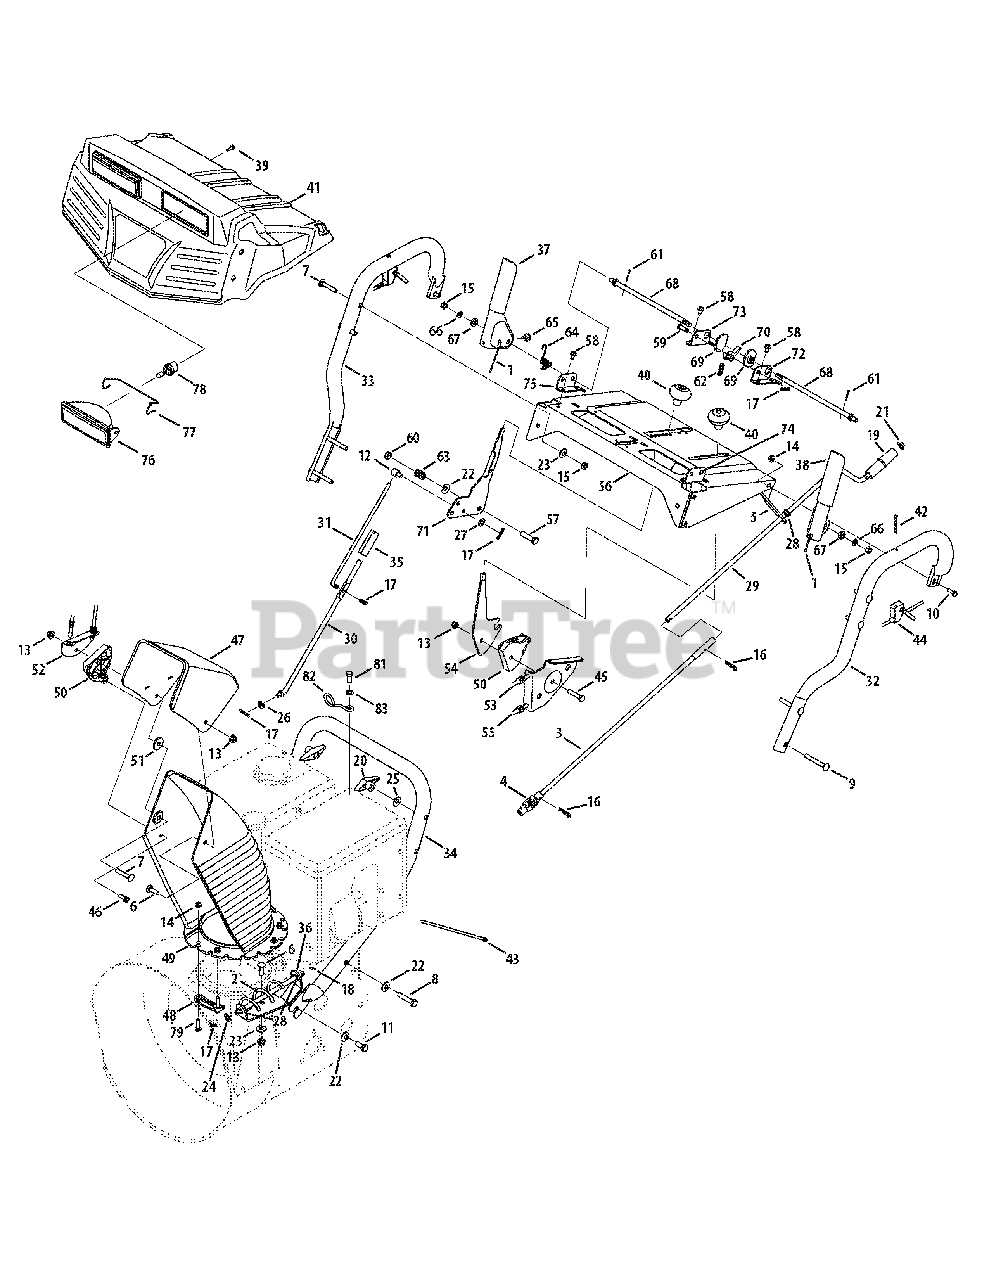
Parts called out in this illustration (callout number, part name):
1	Cable Ass’y, Auger/Drive
2	Chute Crank Assembly
3	Chute Crank Rod Assembly
4	Joint Block Assembly
5	Chute Crank Bracket
6	Carriage Screw, 5/16-18 x 1.0
7	Carriage Screw, 5/16-18 x 1.75
8	Hex Screw, 3/8-16 x 2.00
9	Carriage Screw, 5/16-18 x 2.5
10	Hex Screw, 1/4-20 x .75
11	Screw, Hex, 3/8-16 x 1.00
12	Ferrule, 5/16-18 x .312 Dia
13	Flange Lock Nut 5/16-18
14	Flange Lock Nut 1/4-20
15	Hex Lock Nut, 5/16-18 GR5
16	Internal Cotter Pin
17	Internal Cotter Pin
18	Spring Pin, .156 dia. x .875 Lg.
19	Knob, Crank
20	Wing Knob, 5/16-18
21	Push Cap, 3/8
22	Bell Wash, .375 x .87 x .063
23	Flat Washer, .349 x .879 x .063
24	Flat Wash, .375 x .738 x .063
25	Wash, Bell, .34 x .872 x .06
26	Flat Wash, .344 x .688 x .065
27	Flat Washer, .344 x .750 x .120
28	Plastic Bushing, .38 ID
29	Upper Chute Crank Rod
30	Lower Shift Rod
31	Upper Shift Rod
32	Handle, Upper LH
33	Handle, Upper RH
34	Handle, Lower
35	Shift Rod Connector
36	Chute Crank Bracket
37	Engagement Handle, RH
38	Engagement Handle, LH
39	Screw, #10-16 x .625
40	Shift Knob
41	Handle Panel, 7-Style
42	Screw, #10-24 x 1.75
43	Cable Tie
44	Trigger Control
45	Hex Screw 5/16-18 x 1.5
46	Hex Screw, 1/4-15 x .75
47	Upper Chute, 6.0
48	Chute Flange Keeper
49	Lower Chute
50	Cbl. Guide, Chute Tilt
51	Flat Wash, .344 x 1.125 x .12
52	Cable Bracket
53	Chute Control Cable, 66"
54	Chute Tilt Handle
55	Chute Control Cable w/Clip
56	Handle Panel
57	Hex Screw, 3/8-24 x 1.5
58	Hex Screw, 1/4-20 x .5
59	Clevis Pin, .312 x 1.0
60	Insert Nut, 3/8-24
61	Cotter Pin, 3/32 x .75
62	Compression Spring
63	Compression Spring
64	Torsion Spring
65	Rubber Bumper
66	Lock Washer, 5/16
67	Flat Wash, .35 Sq x .72 x .134
69	Handle Lock Cam
70	Handle Lock Pawl
72	Handle Support Bracket - LH
73	Handle Support Bracket - RH
75	Handle Support Bracket - RH
76	Light Assembly
77	Headlight Retainer
79	Hex Screw 1/4-20 x 1.0
81	Hex Head Screw, MB-1.25
82	Cable Guide
83	Flat Washer, .330 x .630 x .0635
